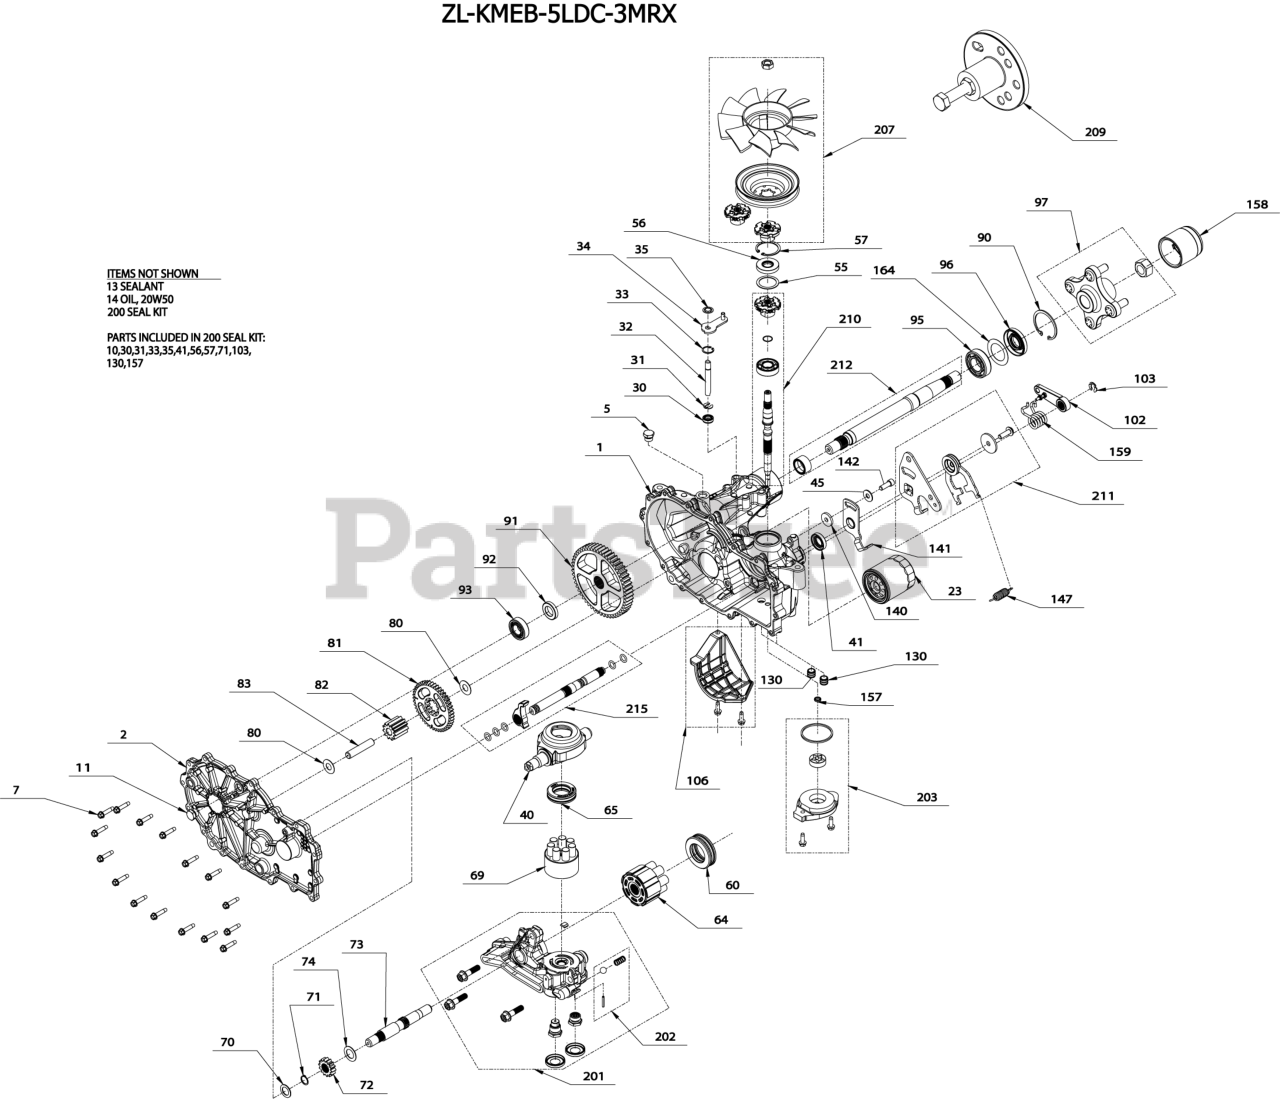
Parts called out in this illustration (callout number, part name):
7	SCREW,HEX WASHER 1/4-20X1.125
13	SEALANT TUBE 10.1OZ.
14	FLUID, HYDRO 15W50 QT
23	FILTER, HYDRO-GEAR 2800 TRANS
30	Seal, lip .375 x 375 x 325
31	RING. RETAINING
32	ROD, BYPASS
33	RING, RET .750
34	HG BYPASS ARM (52370)
35	RING, RTNG .
40	TRUNNION, SWASHPLATE
41	SEAL, LIP 18X32X7
45	WASHER
55	WASHER 1.23X1.56X.04
56	SEAL, LIP 17X40X7
57	RING, RET 1.56 INT
60	HG THRUST BEARING (51462)
64	HG 16CC CYLINDER BLOCK (71579)
65	BEARING. THRUST 30 X 52 X 13
69	ASSY, BLOCK 7 PISTON
70	WASHER .63X1.0X.05
71	RING, RET 62 EXT
72	GEAR 14T STEEL
73	SHAFT, MOTOR
74	WASHER .71 X 1.16 X .04
80	WASHER .5X1.0X.032
81	GEAR 45 TOOTH
82	GEAR 11 TOOTH STEEL
83	JACK SHAFT (PIN)
90	RING, RETAINING
91	GEAR 54 TOOTH
92	SPACER
93	KIT, BEARING
95	BEARING, BALL 25.4 X 52 X 15
96	SEAL, LIP
97	KIT, HUB 4 BOLT
102	HG ACTUATING KIT HANDLE
103	CLIP,BRAKE ARM HYDROGEAR 52027
130	TUBE CHARGE TRIPLE ORING
141	ARM, NEUTRAL LEFT
142	SHCS 5/16-24X1 PATCH
147	SPRING, HYDROGEAR P/N 51833
157	KIT GEROTOR SEAL
158	CAP, AXLE
159	SPRING, TORSION, CW
200	KIT, SEAL
201	KIT, CENTER SECTION, LH CHARGE
202	KIT CHARGE RELIEF
203	KIT, CHARGE
207	KIT, FAN / PULLEY
209	HUB PULLER 5 BLT
210	KIT INPUT SHAFT
211	RING, RTNG .
212	KIT SHAFT AXLE
215	SEAL, LIP 18X32X7
